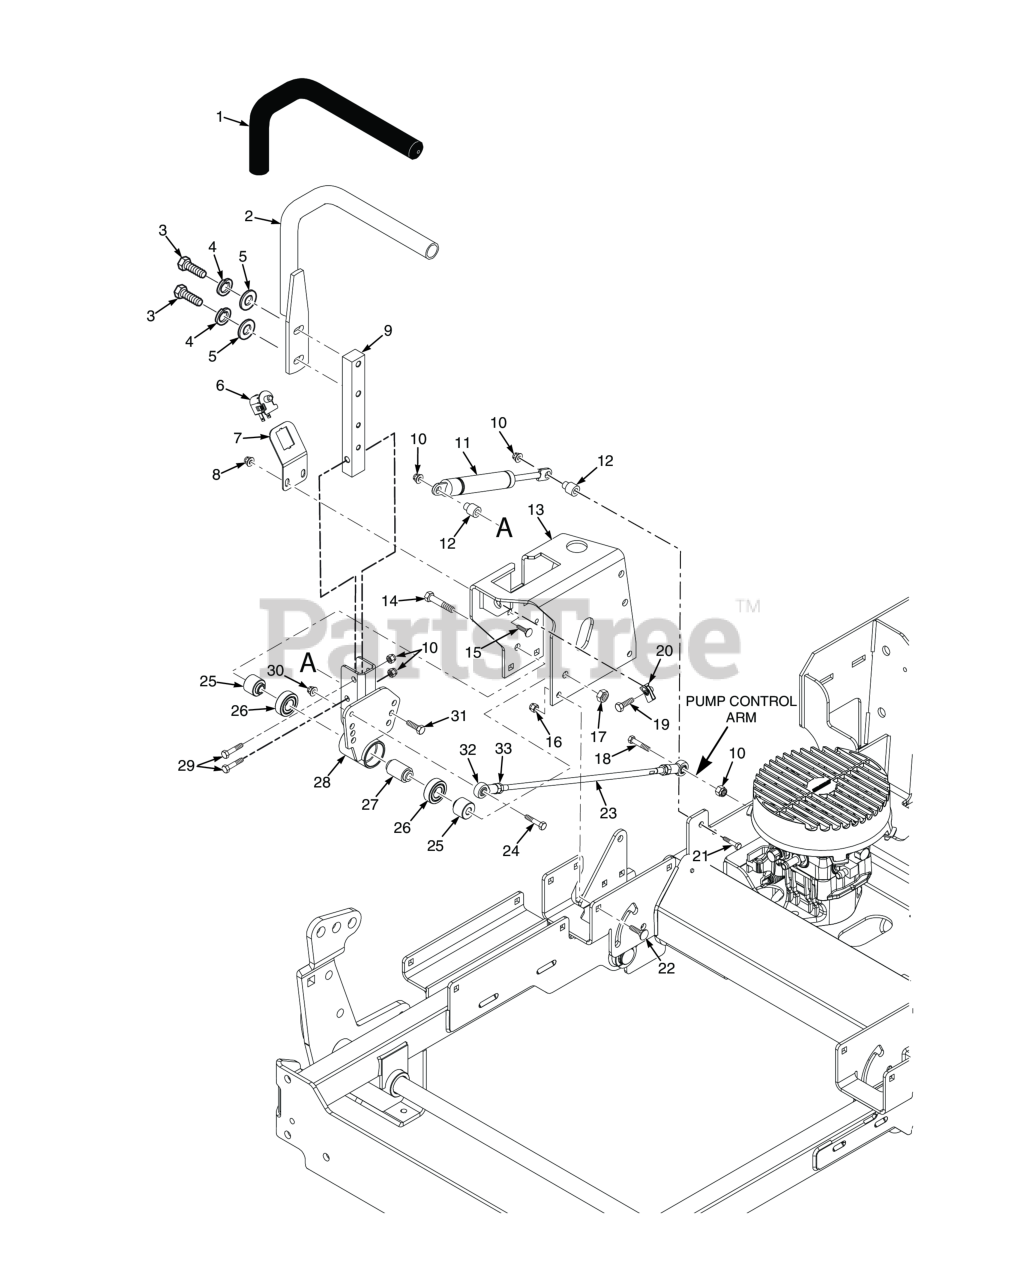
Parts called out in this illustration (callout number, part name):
1	Grip, Control Handle
2	Handle Bar w/Grip
3	Bolt, Hex Head 3/8-16 x 1-1/4", Kawasaki FX / FT & FT-EFI
4	Lockwasher, 3/8" Spring, Kawasaki FX / FT & FT-EFI / B&S 32BV
5	Flatwasher, 3/8" Special (.391 x .938 x .105)
6	Switch, Interlock, Normally Open
7	Bracket, Operator Presence Switch
8	Nut, Flanged Elastic Stop 1/4-20
9	Bar, Control Lever
10	HEX NUT, ELASTIC STOP LOCK, 5/16-18
11	Gas Damper
12	Spacer, Pump Dampener
13	Control Plate w/decal, LH
14	Bolt, Hex Head 3/8-16 x 4-1/4"
15	Serr. Fl. Hex Head CPSCR, 1/4-20 x 3/4"
16	Nut, Serrated Flange 5/16-18 (Right Front Engine Mounting, Briggs and Kohler Only)
17	Bolt, Hex Head 3/8-16 x 1" Ser. Flg.
18	Bolt, Heax Head 5/16-18 x 1" (48V / 52V)
19	Bolt, Hex Head 3/8-16 x 1-1/4" with Thread Lock Patch
20	U-Nut, 3/8-16 (short)
21	Bolt, Hex Head 5/16-18 x 1-1/2" (Right Front Engine Mounting, Briggs and Kohler Only)
22	Bolt, 5/16-18 x .75 RHSN Carriage
23	Linkage Assy, Steering
24	Bolt, Hex Head, 1/4-20 x 1-1/2"
25	Spacer, Controls
26	BEARINGS, BALL, NEUTRAL RETURN
27	Spacer, Bearing
28	Pivot Weldment, Control Arm RH
29	Bolt, Hex Head 5/16-18 x 1-1/2" - Front
30	HEX, NUT, ELASTIC STOP LOCK, 1/4-20
31	Bolt, Hex Head 5/16-18 x 1-1/2" (Right Front Engine Mounting, Briggs and Kohler Only)
32	Rod End, 5/16-24 RH
33	Nut, 5/16-24 UNF Jam LH
